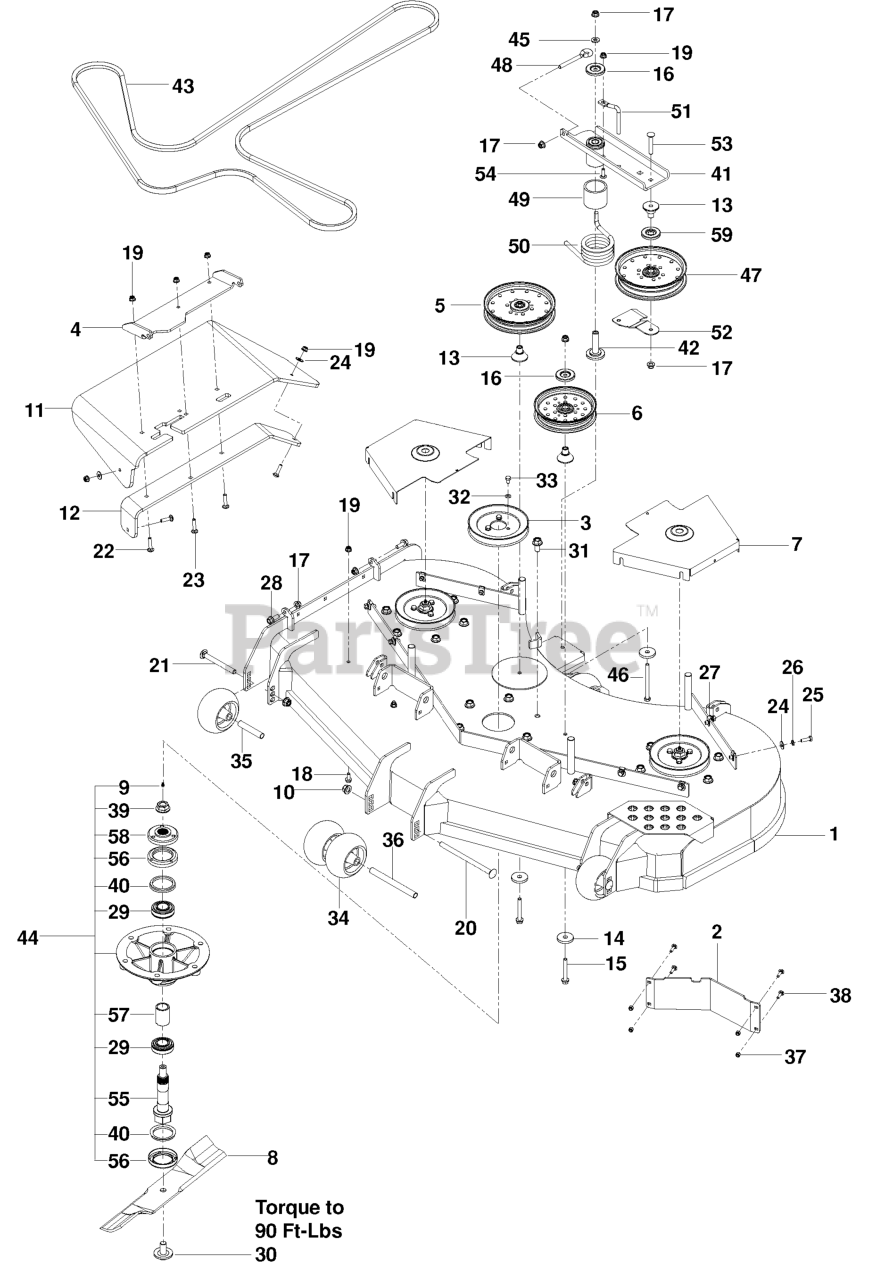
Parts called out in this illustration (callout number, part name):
1	DECK.SVC W/DECALS.60.ORANGE
2	BAFFLE, DIVERTER 54"/60" LH
3	PULLEY - 6.57
4	BRKT - CHUTE MTG BLACK
5	PULLEY - 7" NARROW
6	PULLEY IDLER, 6" NARROW
7	SHIELD,BELT, 60" ORANGE
8	BLADE - HEAVY DUTY 21"
9	ZERK
10	NUT, 1/2-13 HEX FLG NYLOC ZD
11	CHUTE, DISCHARGE 48-52
12	BRKT, CHUTE SUPPORT BLACK
13	BEARING, IDLER ARM
14	SPINDLE WASHER
15	HHFS 3/8-16 X 2 3/4
16	DUST SHIELD
17	NUT 3/8-16 HEX FLG NYLOC ZD
18	HHFS 5/16-18 X 3/4
19	5/16-18 NYLOC FLANGE NUT
20	RHSNB 1/2-13 X 8 GR5 ZD
21	RHSNB 1/2-13 X 4.75 GR5 ZD
22	RHSNB 5/16-18 X 1-1/2 GR 5 ZD
23	BOLT, CARRIAGE 5/16X1-1/4
24	WASHER 5/16 FLAT
25	HCS 5/16C X 1
26	WASHER.LOCK.HVY.HLCL.SPR.5/16
27	U-CLIP 5/16-18 NUT RETAINER
28	HHFS 3/8-16 X 1 GRD 5 ZD
29	BEARING - 206KRR8
30	BLADE BOLT/WASHER
31	HHFS 1/2-13 X 1 GR5 ZD
32	WASH 5/16 DISC SPRING ZD
33	HCS 5/16-18 X 1/2 GR 5 ZD
34	ROLLER, GAUGE .635 BORN
35	TUBE, ROLLER AXLE
36	TUBE, ROLLER AXLE LONG
37	NUT.1/4-20.HEX.NYLOC.ZD
38	1/4-20X3/4 CARR BLT
39	NUT FLANGE 3/4-16
40	V-RING, 55MM
41	ASSY, IDLER ARM, PZ
42	BEARING, IDLER PIVOT
43	BELT, DECK
44	SPINDLE ASM. 10"
45	WASHER, 3/8 THICK
46	HCS 3/8-16 X 4-1/2 GR 8 ZD
47	PULLEY - IDLER 7"
48	EYE BOLT, 3/8 X 4"
49	SPACER, IDLER PIVOT
50	SPRING, TORSION, IDLER
51	BELT KEEPER
52	BELT.GUIDE.BLACK
53	CARRIAGE BOLT 3/8-16 X
54	RHSSNB 5/16C X 1.0
55	SHAFT - SPINDLE
56	CUP - DEBRIS
57	SPACER - BEARING
58	HUB - PULLEY
59	SHIELD, DUST
